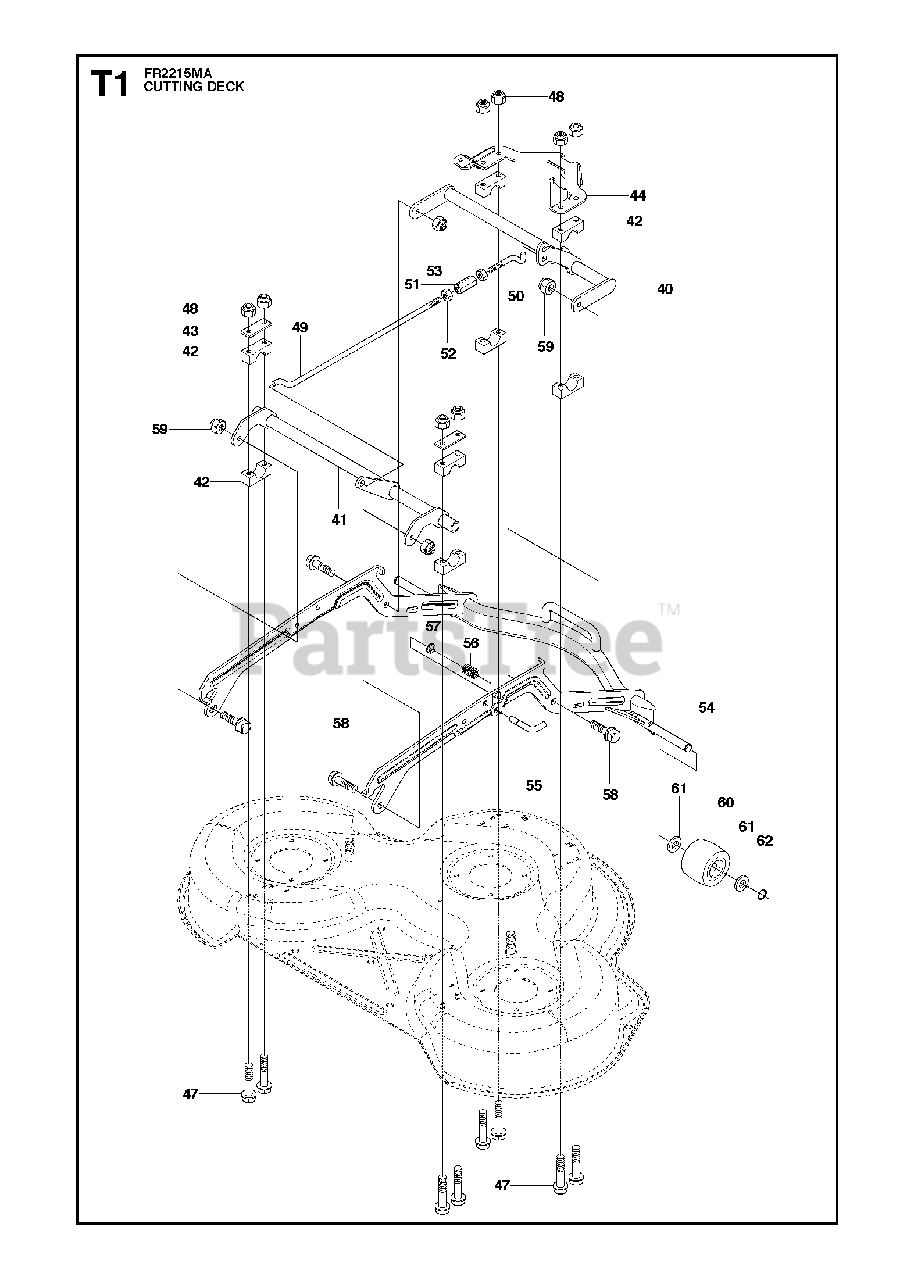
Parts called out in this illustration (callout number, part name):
48	LOCKNUT M8
59	LOCKNUT M8
60	DECK ROLLER, FRONT
62	RETAINING RING SGA 15
